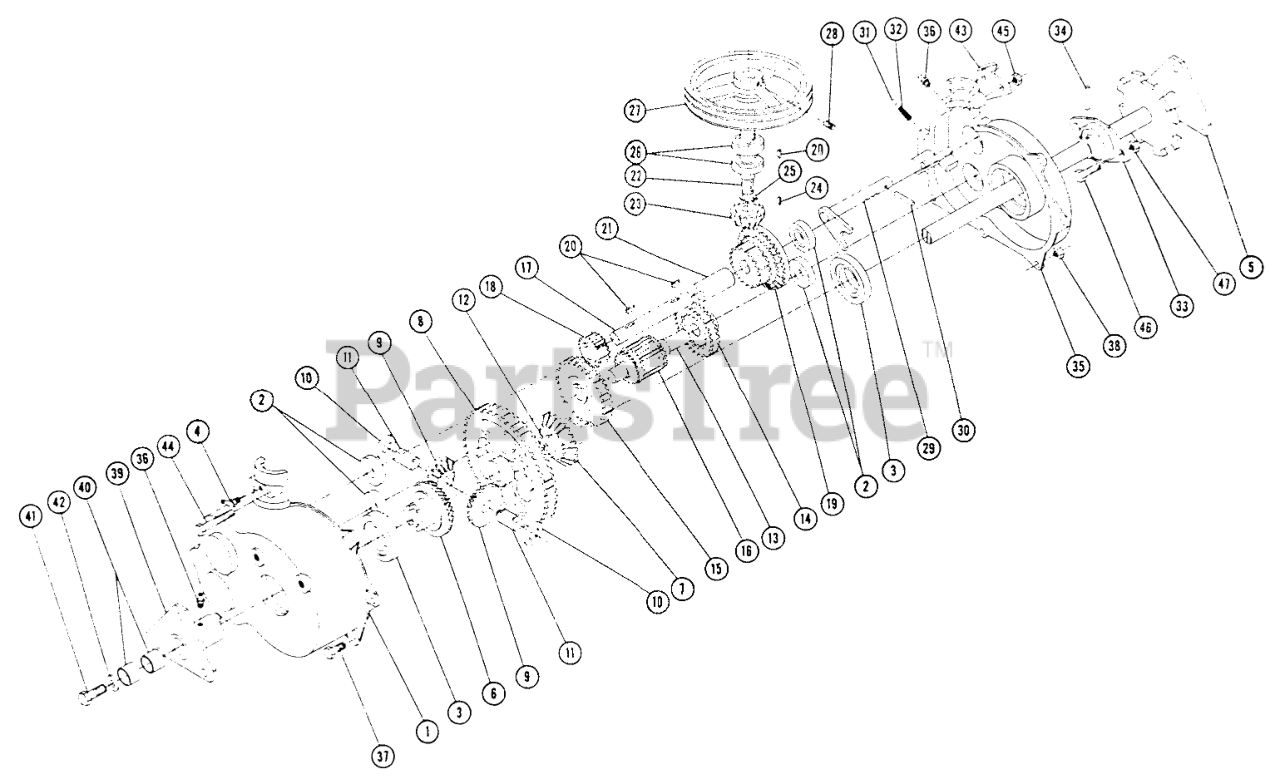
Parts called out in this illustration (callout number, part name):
4	FITTING-GREASE
5	Ass-y. Axle
6	4XC6475 GIS ROTARY
12	WOODRUFF KEY
17	Shaft-Hi Low Pinion
20	Key
21	Spacer
22	Shaft Input
24	WOODRUFF KEY
28	Set Screw 1/4-20 x 3/8
30	PIN-SPIROL
31	BALL-DETENT
34	Spirol Pin
37	Bolt, 5/16-18 X 7/8
38	Nut 5/16-18
39	Ass-y Hub Flange
40	BUSHING-BRONZE
41	Bolt 3/8-16 x 3/4 Hex
42	WASHER
43	Bracket-Shift Rod
44	Bolt Hex 5/6-18 X 2-1/2
45	Nut-Nylok
46	Bolt Hex 3/8-16 x 5/8
